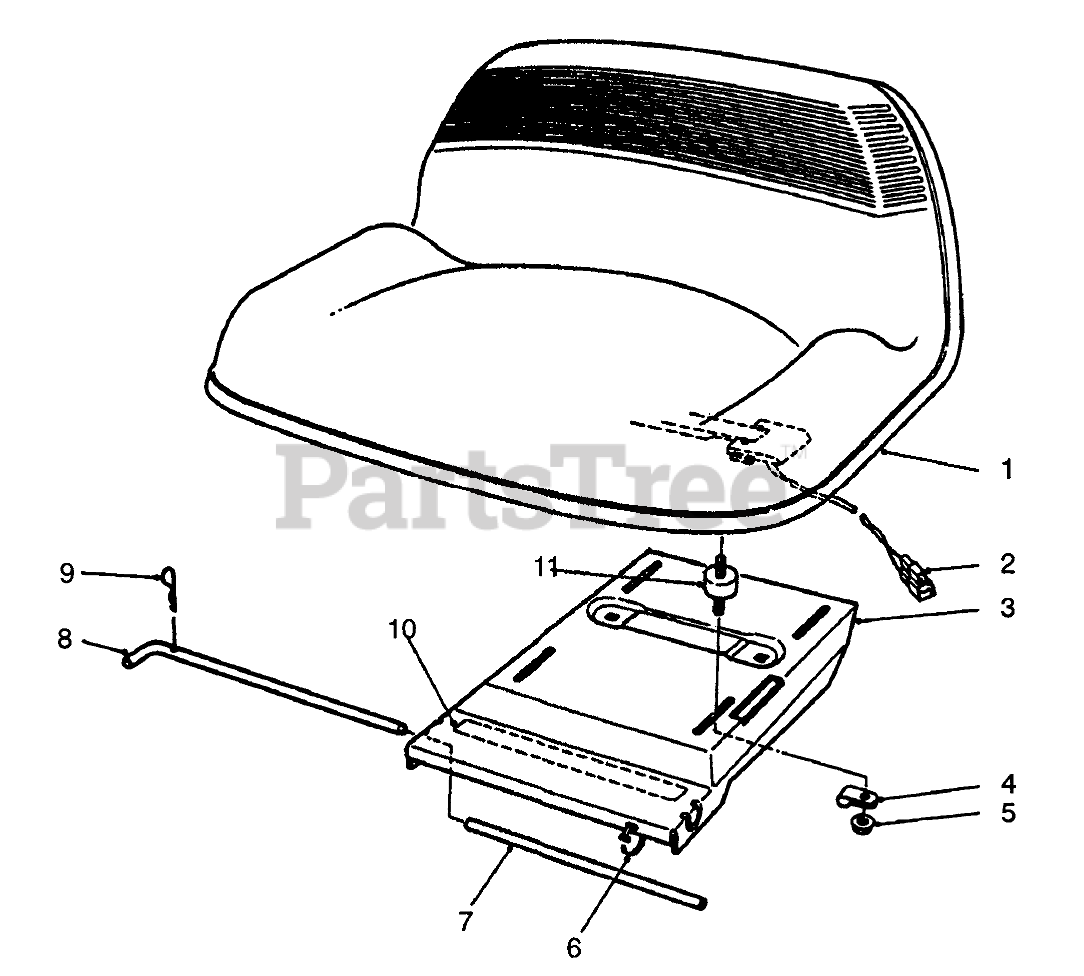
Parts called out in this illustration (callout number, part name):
1	Seat
2	SWITCH-SEAT
3	Base-Seat
4	CLAMP
5	NUT-HF
6	TIE-CABLE
7	TUBE-SEAT
8	ROD-SEAT BASE
9	PIN-COTTER
10	DECAL
11	ISOLATER-SEAT
